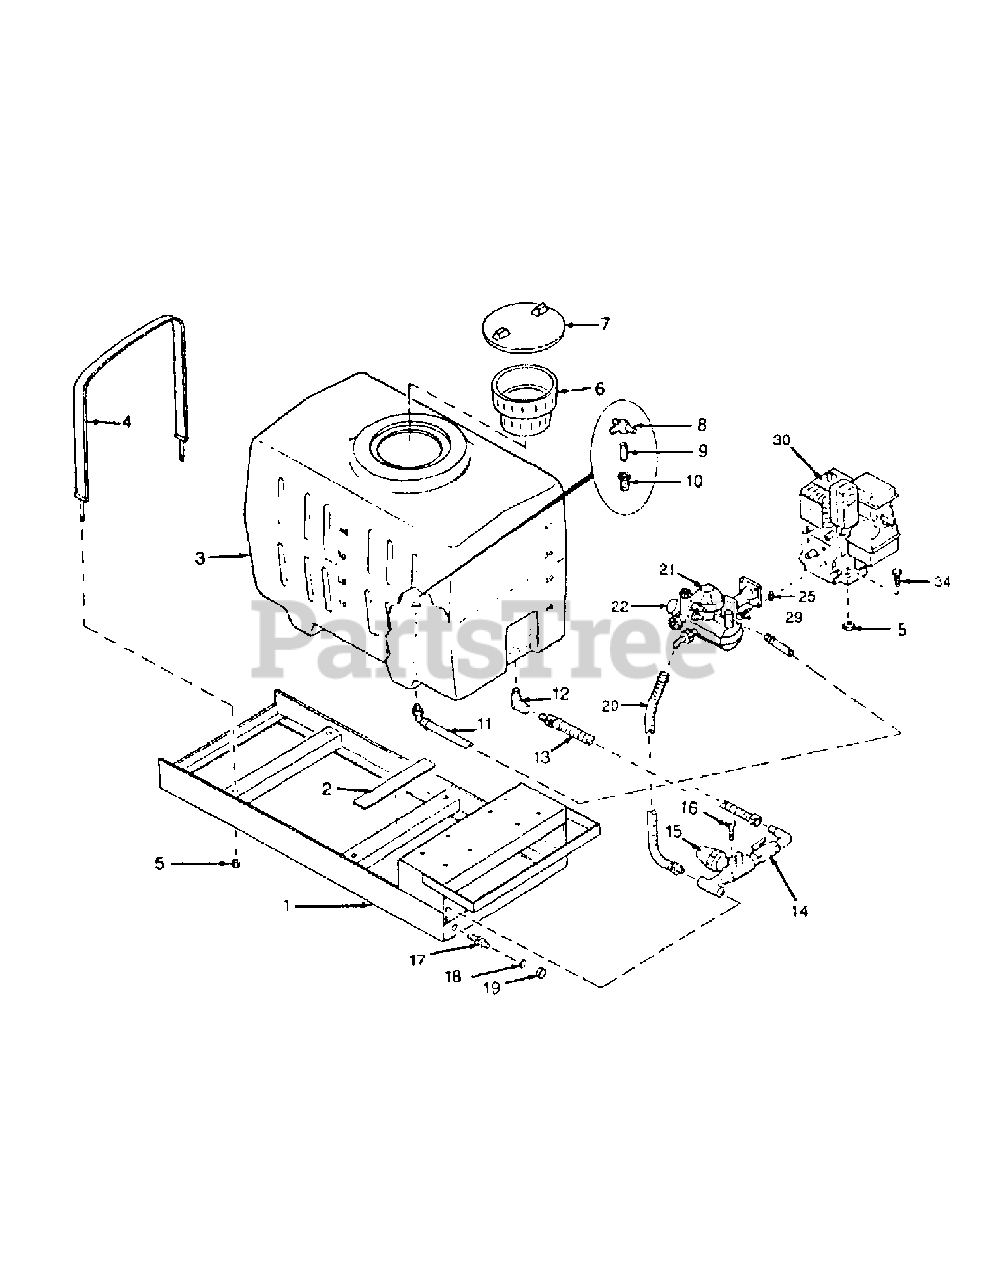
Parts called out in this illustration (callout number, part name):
1	Frame
2	Foam, Adhesive Backed, 4"x 1/4'x 16-1/2
3	Rect. Poly Tank, 50-Gallon
3	Fillwell, 1 0", Threaded
4	Tank Strap w/2 T-Bolts
5	Hex Nut, 5/16-18 Nylock
6	Strainer Basket 10"
7	Tank Lid, 10"
8	Agitator, Triple Jet, Brass
9	Nipple, 1/4 x Close, Brass
10	Reducer, 1/2 MPT x 1/4 FPT, Brass
11	Agitator Hose
12	Street Elbow, 9O Degree, 3/4 MPT x 3/4 FPT, PVC
13	Suction Hose, Tank to Manifold
14	Manifold Assembly
15	Line Strainer, 30 Mesh, 3/4 FPT x 3/4 FPT, PVC
15	Repair Kit
15	32 Mesh Screen
15	50 Mesh Screen
15	100 Mesh Screen
16	Cap Screw, 8MM-1.25 x 12 MM, Hex Hd:, Serrated Flange
17	Adapter, 3/4 MPT x 3/4 NH(M), Brass
18	Hose Washer, 3/4
19	Hose Cap, 3/4 NH(F), Brass
20	Suction Hose, Manifold to Pump
21	Pump, Twin Diaphragm
21	Pump, Diaphragm Repair Kit
22	Control Unit
25	Flat Washer, 5/16
29	Cap Screw, 5/16-24 x 3/4 Hex Hd
30	Engine, 4-HP, KAW., Recoil Start
30	Air Filter for KAW. Engine
30	Spark Plug for KAW. Engine
31	Nipple, 1/4 MPT x 1-1/2, Galv.
32	Elbow, 90 Degree, 1/4 FPT x 1/4 FPT, Galv.
33	Plug, 1/4 MPT, Square Head
34	Cap Screw, 5/16-18 x 1-3/4 Hex Hd.
